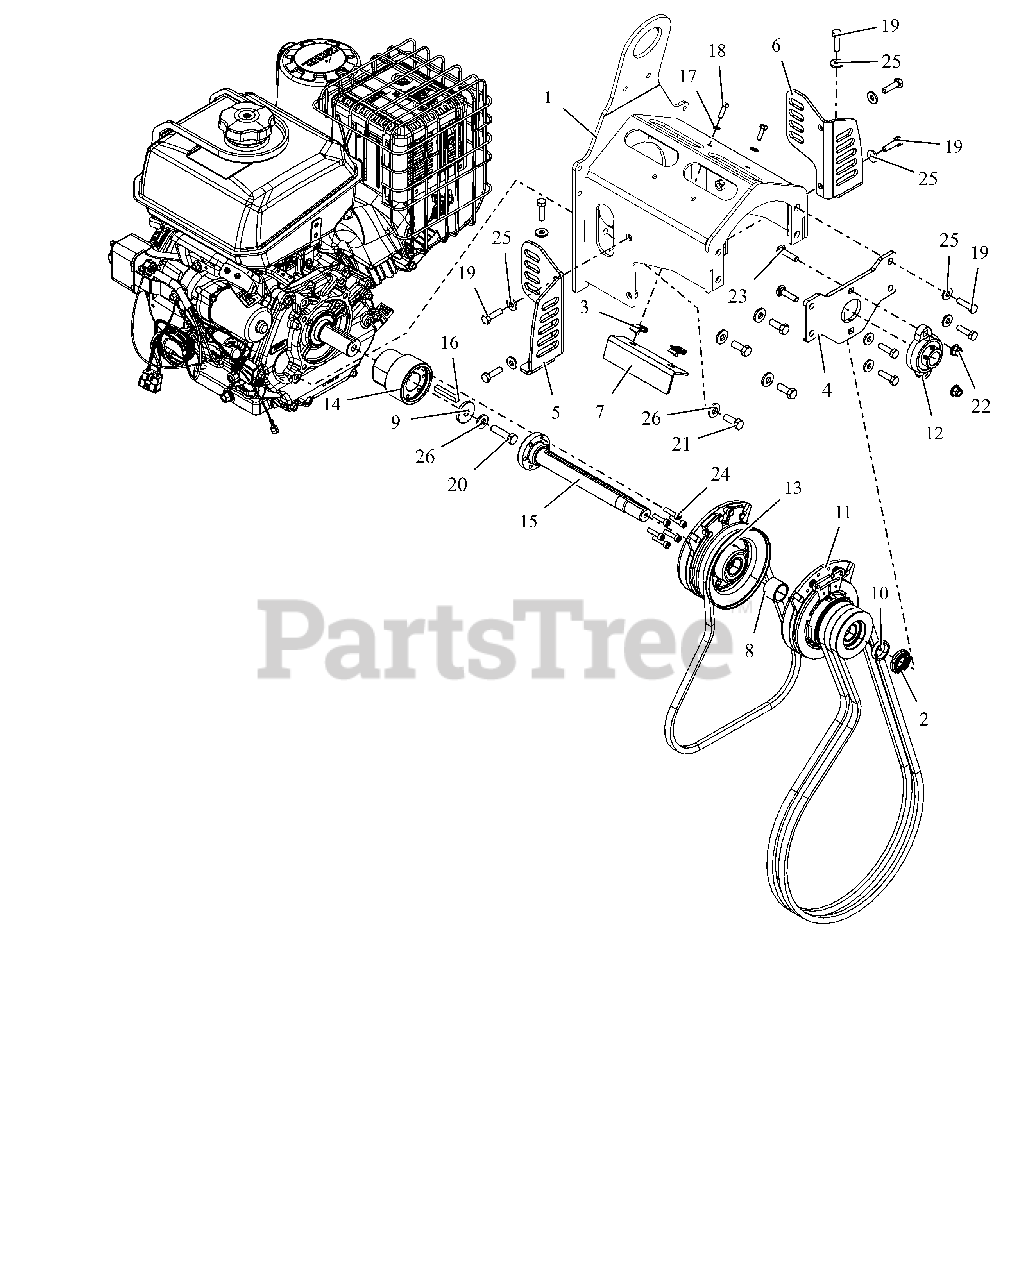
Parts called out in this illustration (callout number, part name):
1	WLDMT, CRANK SHAFT SUPPORT
2	NUT, BRG-LK M25X1.5 ZC120
3	NUT-RTNR M6X1
4	PLATE, FACE CRANK SUPPORT
5	BRKT, ENCLOSURE RH
6	BRKT, ENCLOSURE LH
7	BRKT, CLUTCH STOP
8	SPCR, CLUTCH
9	WSHR, COUPLER .394X1.438X.188
10	SPCR, BRG NUT
11	CLUTCH, PTO DOUBLE GROOVE
12	BRG, FLANGE FX205
13	CLUTCH, TRANS RMS
14	COUPLER, SHAFT EXTENSION
15	CRANK, SHAFT EXTENSION
16	KEY, 7MM X 46MM
17	WSHR,LK-REG .250X.062 ZCC
18	BLT, HEX M6-1.0 X 20 G8.8 ZCC
19	BLT, HEX M8-1.25X30 8.8CRKFCTR
20	BLT,HEX M10-1.25X40FT10.9CRKFC
21	BLT, HEX .38-16X1.00 G5 CKF
22	NUT,NYL-FLG M8-1.25 G8.8 ZCC
23	BLT,RDHDSQNK M8-1.25X35 8.8ZC1
24	SCR,SKH M6-1.0X25 10.9CRKFCTR
25	WSHR,BLVL M8X19.84X2.5 ZCMCH
26	WSHR,BLVL,M10 X 25 X 3.9 ZCMCH
